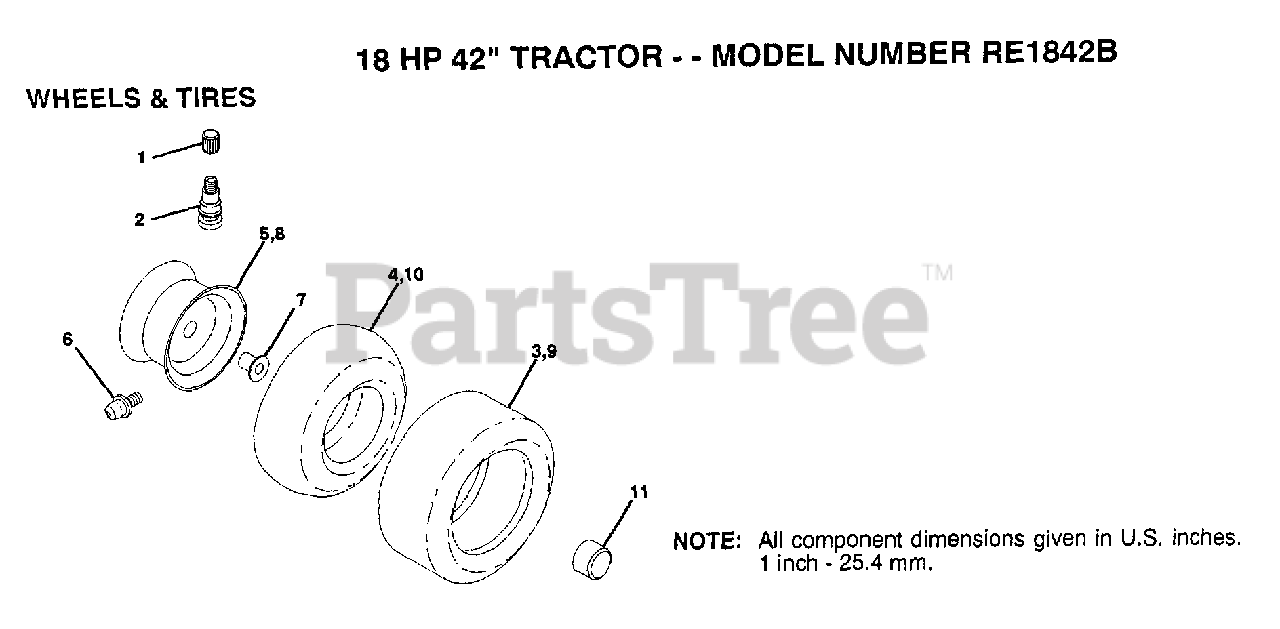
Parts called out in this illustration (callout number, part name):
1	VALVE CAP
2	VALVE STEM LT
4	TUBE.5.3/4.5/6
6	FITTING LT
7	"FLANGE, BEARING"
10	TUBE.18X9.5-8
11	HUB CAP
